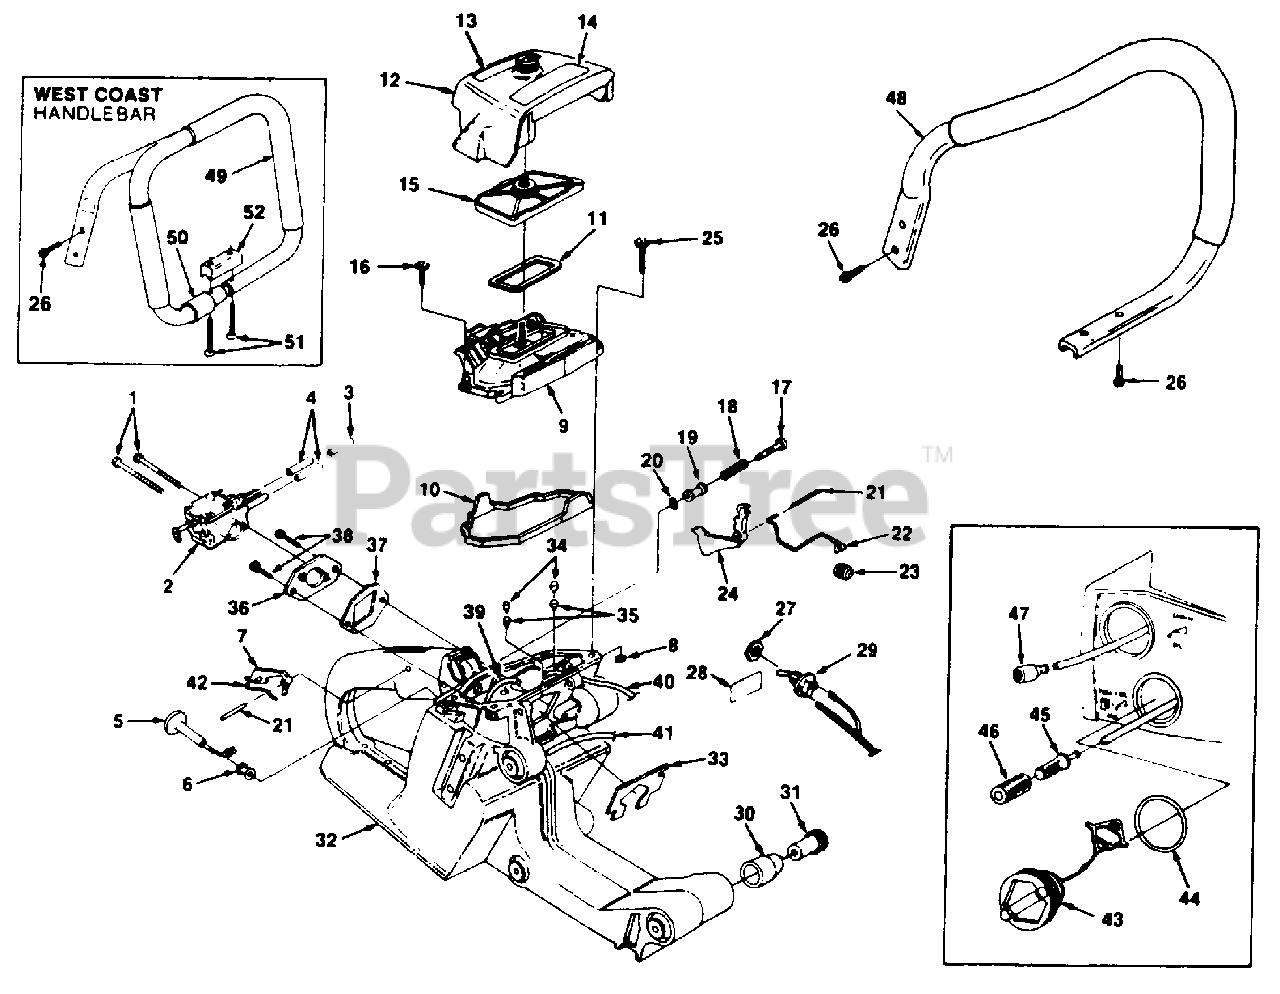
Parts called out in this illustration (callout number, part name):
1	SCREW- Mach Hex hd. (10-24 x 2")
2	CARBURETOR-(WJ-2)
5	ROD- Choke
6	GROMMET
7	TRIGGER- Lock
8	NUT 8-32
9	COVER- Carburetor chamber
10	GASKET- Carburetor chamber
11	GASKET- Air filter
12	COVER- Air filter
13	DECAL- Warning
14	DECAL Warning
15	ELEMENT- Filter
16	SCREW- (8-32 x 3/8")
17	PIN- Throttle lock
18	SPRING- Compression
19	BUSHING- Flanged
20	RING- Retaining
21	PIN- Trigger
22	ROD- Throttle
23	BOOT- Throttle rod
24	TRIGGER- Throttle
25	SCREW Pan head 8-32 x 5/8
26	SCREW- Thread forming (12 x 3/4")
27	NUT- Hex
28	DECAL- Run Stop
29	SWITCH- Toggle
30	ISOLATOR- Vibration
31	SLEEVE- Flanged
32	HOUSING- Engine
33	BRACKET
34	FILTER ELEMENT
35	VALVE- Duck bill
36	ADAPTOR- Carburetor
37	GASKET- Carburetor
38	SCREW- Hex hd. (10-24 x 1/2")
39	TUBING- Rubber (fuel line) 5 3/4"
40	TUBING- Rubber (pulse line)
41	TUBING- Rubber (oil line)
42	SPRING- Flat
43	CAP- Fuel & Oil
44	"O" RING
45	FILTER- Fuel
46	ELEMENT- Felt filter
47	OIL FINDER
48	HANDLEBAR
49	HANDLEBAR (West Coast Models)
50	BUSHING
